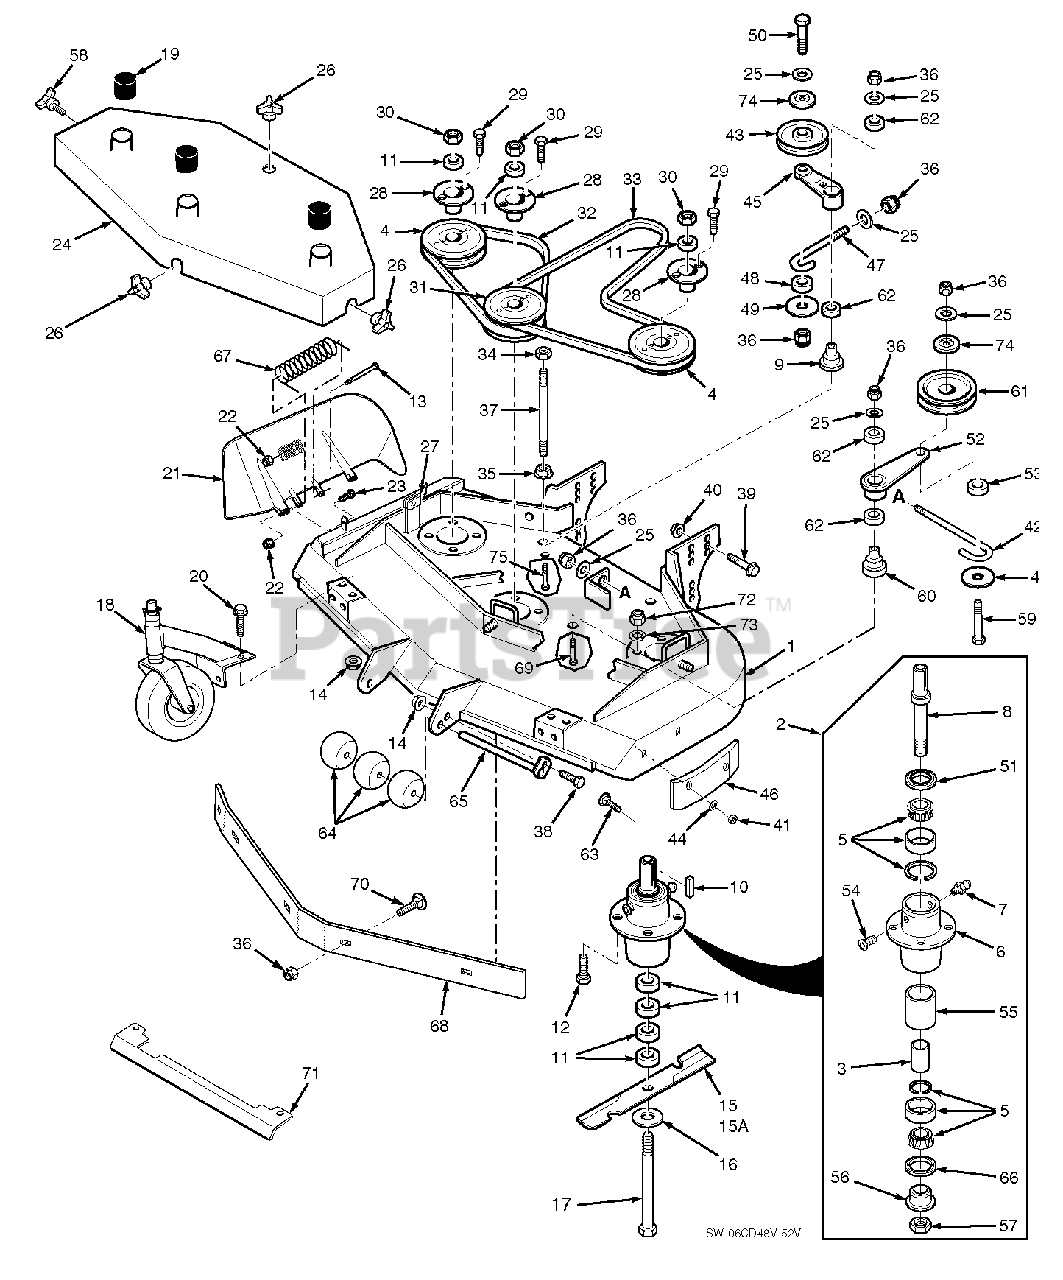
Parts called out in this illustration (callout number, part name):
1	Cutter Deck w/Decals
1	Cutter Deck w/Decals - LE
2	Spindle Assembly
3	Spacer, Inside
4	Pulley
5	Tapered Bearing
6	Spindle Housing
7	Grease Fitting Str. 5/16"
8	Spindle Shaft
9	Idler Pivot
10	Key, 1/4 x 1/4 x 2"
11	Spacer, Cutter Blade - Small
12	Bolt, 5/16-18 x 1-1/2" Hex Head Gr. 8
13	Bolt, 5/16-18 x 4-3/4" Hex Head
14	Serr. Flange Nut, 5/16-18
15	Cutter Blade 16-1/2"
15	Cutter Blade 18"
15A	Cutter Blade 16-1/2 Hi-Lift
15A	Cutter Blade 18 Hi-Lift
16	Flatwasher,5/8" (.688 x 1.75 x .134)
17	Hex Head Bolt, 5/8-11 x 9-1/2"
18	Caster Assembly
19	Spindle Shield
20	Capscrew, 5/16-18 x 3/4"
21	Discharge Chute 48V
21	Discharge Chute 52V
22	Nut, 5/16-18 Elastic Elastic Stop
23	Bolt, 5/16-18 x 1-1/2" Hex Head
24	Belt Cover
25	Flat Washer, 3/8" Special
26	Wing Nut, 3/8-16
27	U-Nut, 3/8-16
28	Tapered Hub
29	Bolt, 1/4-20 x 1" Hex Head Grade 8
30	Nut, 5/8-11 Hex
31	Pulley, Double
32	Belt, RH Blade Drive
33	Belt, Blade Drive
34	Nut, 3/8-16, Nut Centerlock
35	Nut, 3/8-16, Serrated Flange
36	Nut, 3/8-16 Elastic Stop
37	Bolt, 5/16-18 x 1" Hex Head
38	Bolt, 5/16-18 x 1" Hex Head
39	Cpscrw, 1/2-13 x 1" Ser.Flg. HH
40	Nut, 1/2-13 Spiralock
41	Hex Nut, 5/16-18 Center Locknut
42	J-Hook, 48V
42	J-Hook, 52V
43	Idler Pulley, "V" Groove
44	Flatwasher, 5/16"
45	Idler Arm Assy.
46	Pad, Deck Wear
47	J-Rod, Idler Pulley
48	Spacer, J-Rod
49	Washer, 3/8 x 1-1/2 x 16 ga.
50	Bolt, 3/8-16 x 2-1/2" Hex Head
51	Seal, Cutter Spindle
52	Idler Arm Assy
53	Spacer, J-Rod
54	Reiief Fitting, Cutter Spindle
55	Spacer, Outside, Cutter Spindle
56	Spindle Bushing
57	Nut, Cutter Spindle
58	Knob, w/stud
59	Bolt, 3/8-16 x 3-3/4" Hex Head
60	Idler Pivot
61	Idler Pulley, Belt Clutch
62	Bearing
63	Bolt, Carriage 5/16-18 x 3/4"
64	Guide Roller
65	Roller Shaft
66	Seal, Cutter Spindle
67	Spring, Chute Return
68	Baffle Weldment 48V
68	Baffle Weldment 52V
69	Bolt, 3/8-16 x 3-1/4" Hex Head
70	Bolt, Carriage 3/8-16 x 1"
71	Heatshield
72	Nut, Hex Lock 5/16-18
73	Lock Washer 5/16"
74	Dust Shield
75	Bolt, 3/8-16 x 2-3/4" Hex Head
